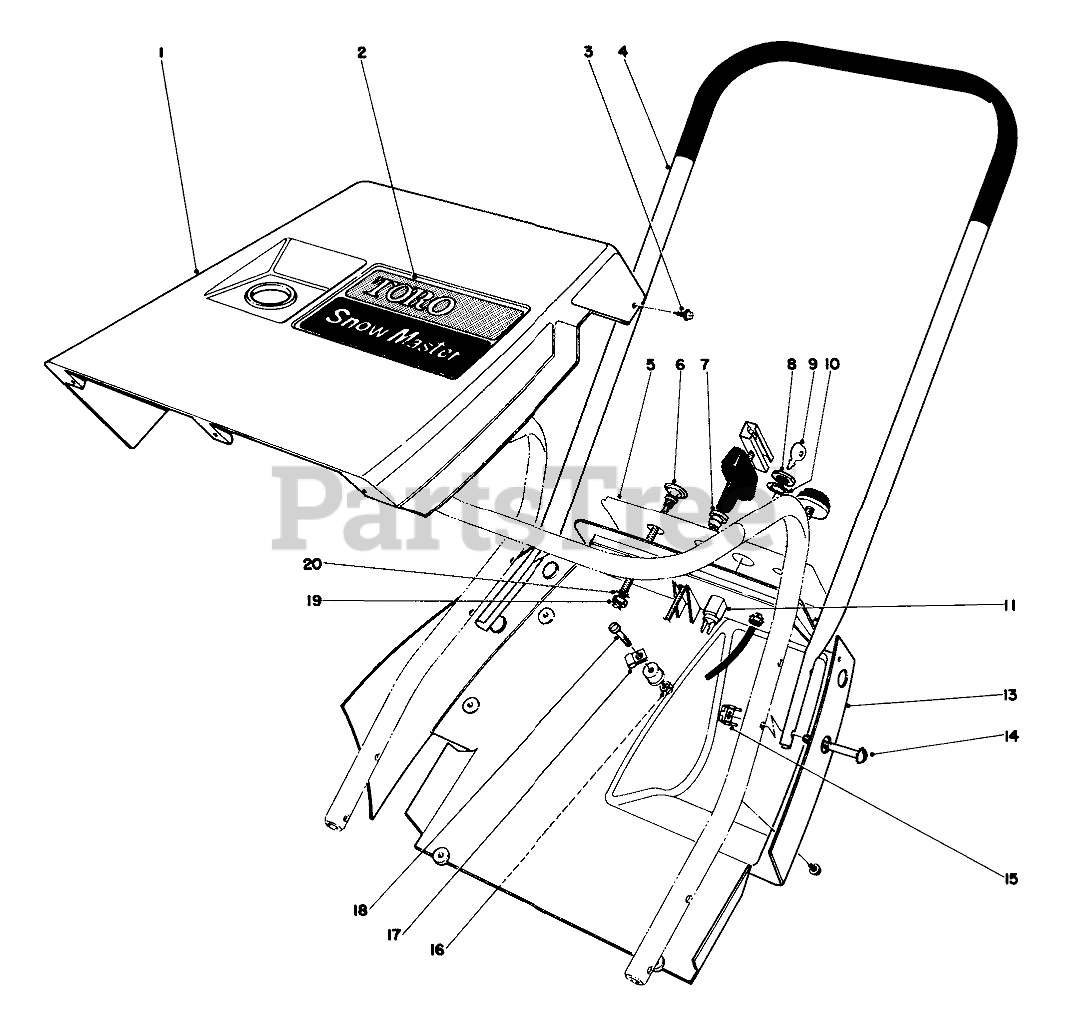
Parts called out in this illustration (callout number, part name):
1	Upper Shroud
2	Decal Toro
3	SCREW-HWHTF
4	Upper Handle
5	Decal-Central Panel
6	Choke
7	GUIDE-ROPE, STARTER
8	NUT-HH
9	Key
10	WASHER-TOOTH, INTERNAL
11	Switch
13	Lower Shroud
14	Sems Mach. Screw
15	TINNERMAN NUT
16	NUT-LOCK, NI
17	3/16 SUPPORT
18	SCREW-PTH
19	NUT-HJ
20	WASHER-LOCK
